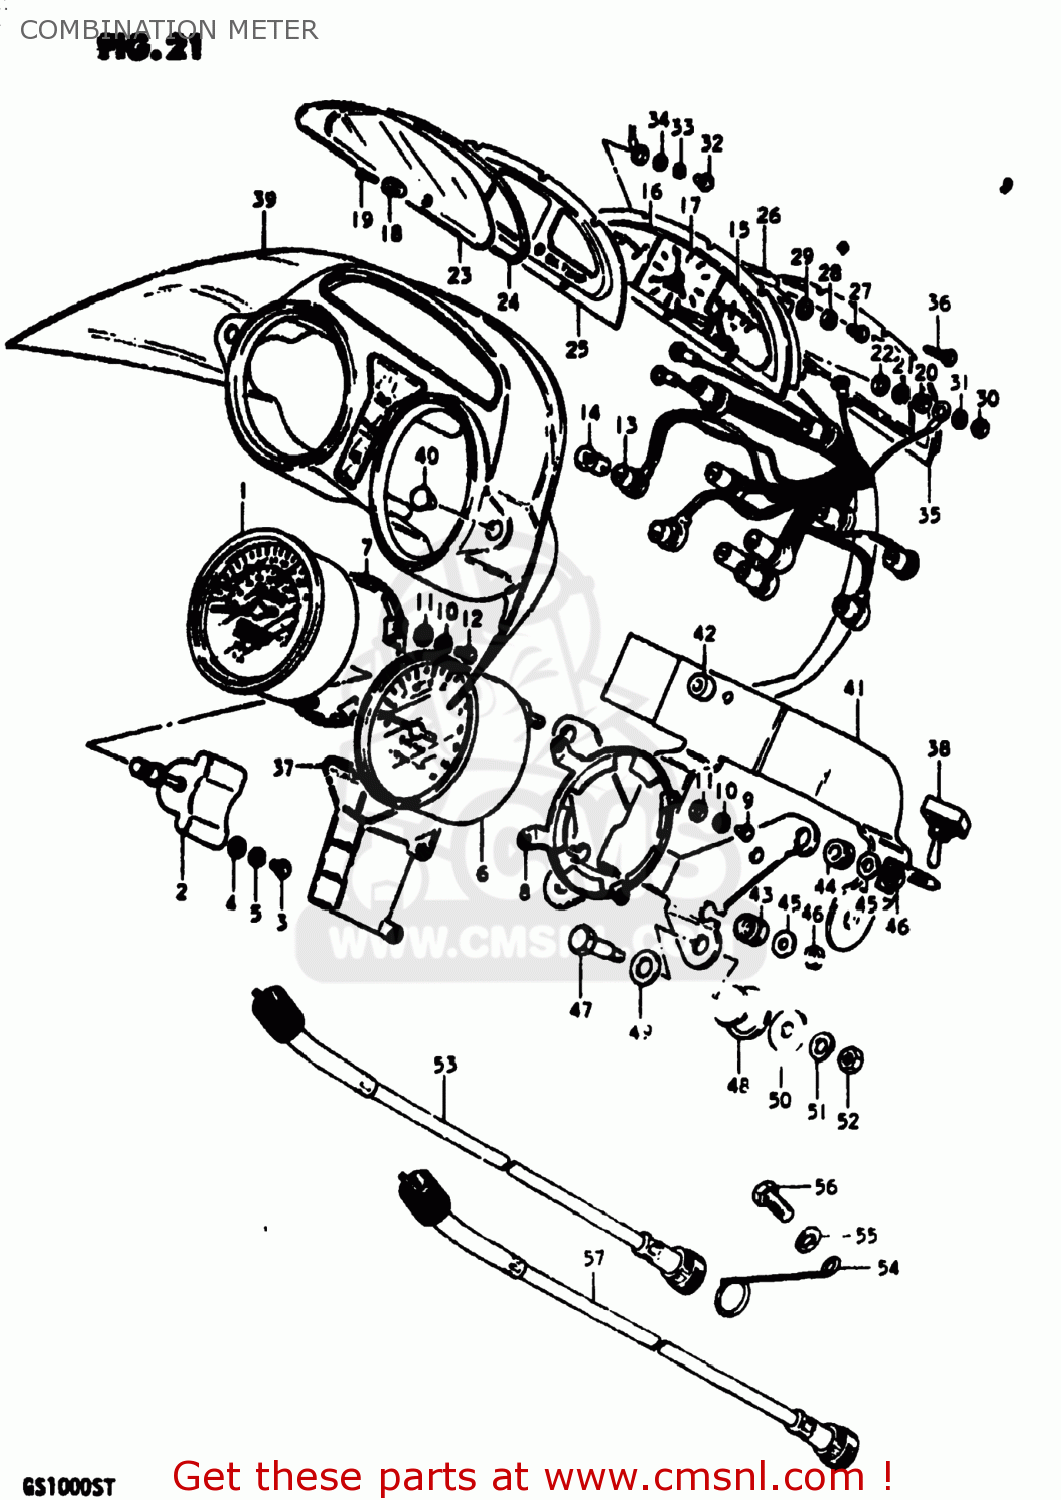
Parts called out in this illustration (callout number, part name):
1	METER,SPEEDOMETER (KM/MPH)
2	HOLDER,TRIP METER RESET
3	SCREW
4	WASHER
5	LOCK WASHER
6	TACHOMETER
7	HOLDER,METER
8	HOLDER,TACHOMETER
9	SCREW
10	LOCK WASHER
11	WASHER
12	SCREW
13	SOCKET,METER
14	BULB(12V3.4W,STANLEY,A72A)
15	METER,OIL TEMPERATURE
16	FUEL METER
17	CLOCK ASSEMBLY
18	KNOB
19	SCREW,CLOCK KNOB
20	NUT
21	LOCK WASHER
22	WASHER
23	GLASS,COMBINED FUEL METER
24	GASKET,COMBINED FUEL METER
25	PLATE,COMBINED FUEL METER
26	CASE,LOWER
27	SCREW
28	LOCK WASHER
29	WASHER
30	NUT
31	LOCK WASHER
32	SCREW
33	LOCK WASHER
34	WASHER
35	BRACKET,FUEL METER
36	SCREW,METER
37	CASE,PILOT BULB
38	SWITCH,CLOCK
39	HOOD,METER
40	CAP,ACCESSORY HOLE
41	BRACKET,COMBINATION METER
42	CUSHION,FUEL METER
43	CUSHION
44	CUSHION,SPEEDOMETER
45	WASHER,SPEEDOMETER
46	NUT
47	BOLT
48	CUSHION,METER
49	WASHER
50	WASHER(8.5X23X1.2)
51	LOCK WASHER
52	NUT
53	CABLE ASSEMBLY,SPEEDOMETER
54	CLAMP,SPEEDOMETER CABLE
55	WASHER
56	BOLT, UPPER
57	CABLE ASSEMBLY,TACHOMETER
